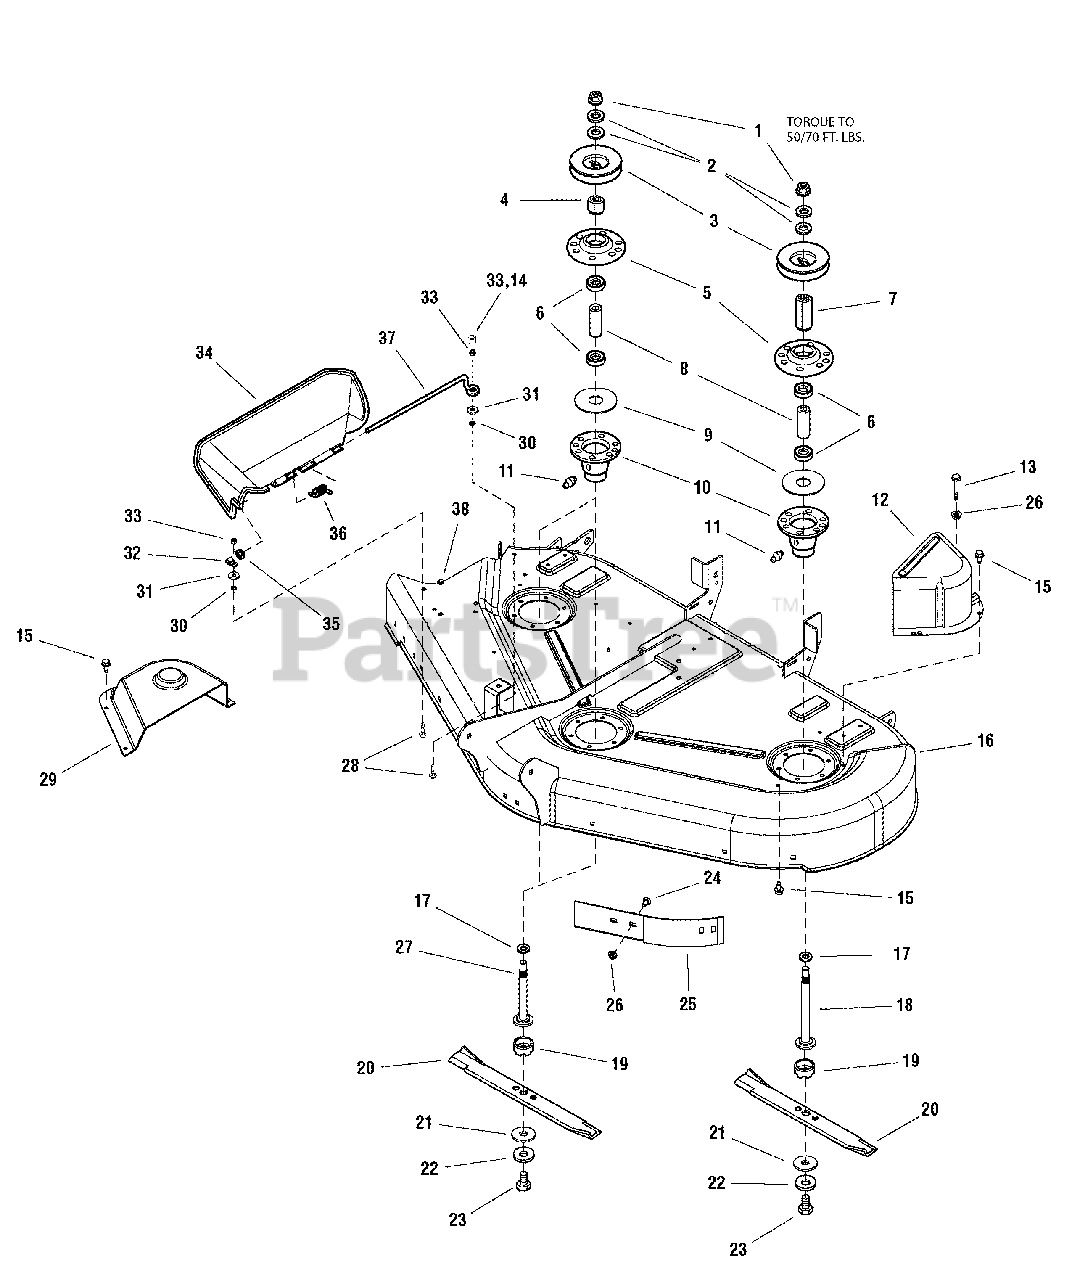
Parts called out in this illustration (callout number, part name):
1	NUT, Hex, Flange, 9/16-8
2	WASHER, Bellville, 9/16
3	PULLEY, RH Arbor & LH Arbor, 4-1/2
4	HUB, Pulley, RH
5	COVER, Arbor Housing
6	BEARING
7	HUB, Adapter, LH
8	SPACER
9	GASKET, Foam
10	HOUSING, Arbor Bottom, w/Lube Fitting
11	FITTING, Grease
12	COVER, Arbor
13	CAPSCREW, Hex Head, Serrated Flange Taptite, 5/16-18 x 2 G5
14	NUT, 1/4-20
15	CAPSCREW, Hex Head, Taptite, 5/16-18 x 3/4
16	HOUSING ASSEMBLY, 50" Frame Hung
17	WASHER
18	SHAFT, Arbor
19	SHIELD, Grass, Lower
20	BLADE, 18-1/8, 50" Deck
21	WASHER, Hex
22	WASHER, Spring
23	CAPSCREW, Hex Head, 7/16-14 x 1-1/4
24	BOLT, Carriage, 5/16-18 x 3/4
25	BAFFLE, Anti-Blowout
26	NUT, Hex, Flange Whizlock, 5/16-18
27	SHAFT, Arbor, RH
28	CARRIAGE BOLT, 1/4-20 x 1, Black
29	COVER, Arbor, RH
30	NUT, Push On
31	WASHER, Plain, 1/4 (6 Total for Export)
32	CLAMP
33	NUT, Hex Lock, ESNA, 1/4-20
34	DEFLECTOR, Plastic
35	WASHER, Flat, 5/16
36	SPRING
37	ROD, Deflector, Front
38	PLUG, Plastic
